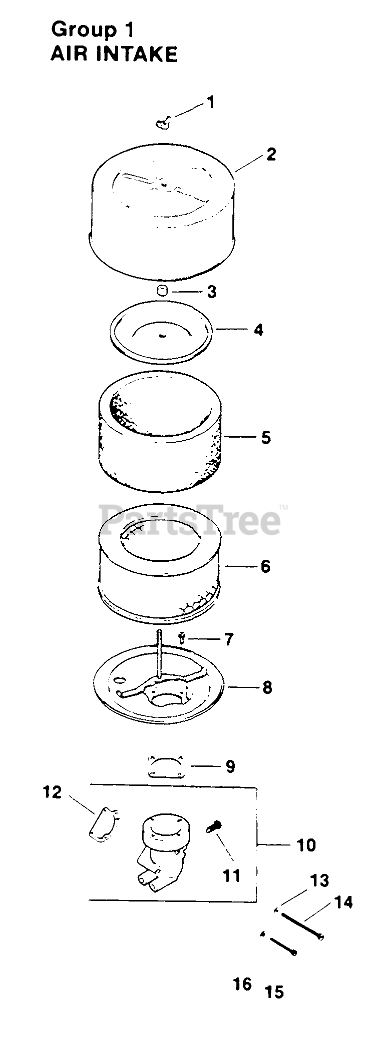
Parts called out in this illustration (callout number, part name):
1	Nut-Wing
2	Cover-Air Cleaner
3	Seal
4	Cover-Element
5	Precleaner
6	Element
7	Screw-H.C.
8	Base-Air Cleaner
9	Gasket-Air Cleaner
10	Elbow-Kit (Incl. Ref. #11 & 12)
11	Screw-Self Tap
12	Gasket-Elbow
13	Washer-Flat
14	Screw-R.H.M.
15	Screw-R.H.M.
16	Washer
